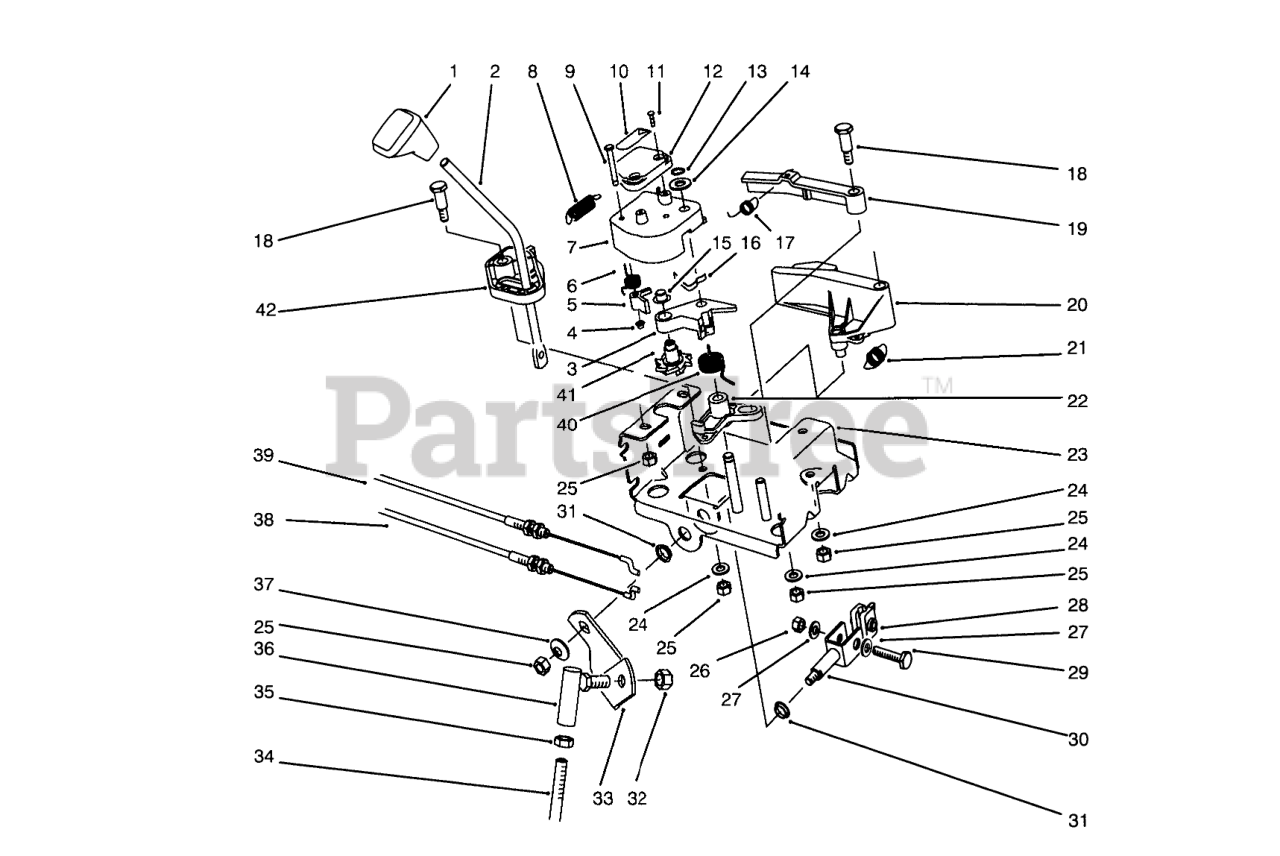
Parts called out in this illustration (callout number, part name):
1	KNOB-SHIFT
2	ROD-SHIFT
3	LEVER-WHEEL, INDEX
4	NUT-PUSH
5	TANG-INDEX
6	SPRING-TORSION
7	LATCH-LEVER
8	SPRING-EXTENSION
9	PIN-TANG
10	DECAL
11	SCREW-PPH
12	COVER-LATCH
13	RING-RETAINING
14	WASHER-THRUST
15	RETAINER-PUSH ON
16	SPRING-FLAT
17	SPRING-EXTENSION
18	SCREW-SHOULDER
19	LEVER-LOCKOUT
20	LEVER-REVERSE
21	SPRING-EXTENSION
22	LEVER-REVERSE, SWITCH
23	Frame-Control
24	WASHER-PLAIN
25	NUT-LOCK, NI
26	NUT-LOCK, NI
27	WASHER-FLAT
28	RETAINER-ROD, SHIFT
29	SCREW-HH
30	CLEVIS ASM
31	BUSHING
32	NUT-LOCK, NI
33	BRACKET-SHIFT
34	ROD-BENT SHIFT, LOWER
35	NUT-HJ
36	JOINT-BALL
37	WASHER-BELLEVILLE
38	CABLE-GEARBOX
39	CABLE-ARM, LATCH
40	SPRING-TORSION
41	WHEEL-INDEX
42	BASE-LOCKOUT
